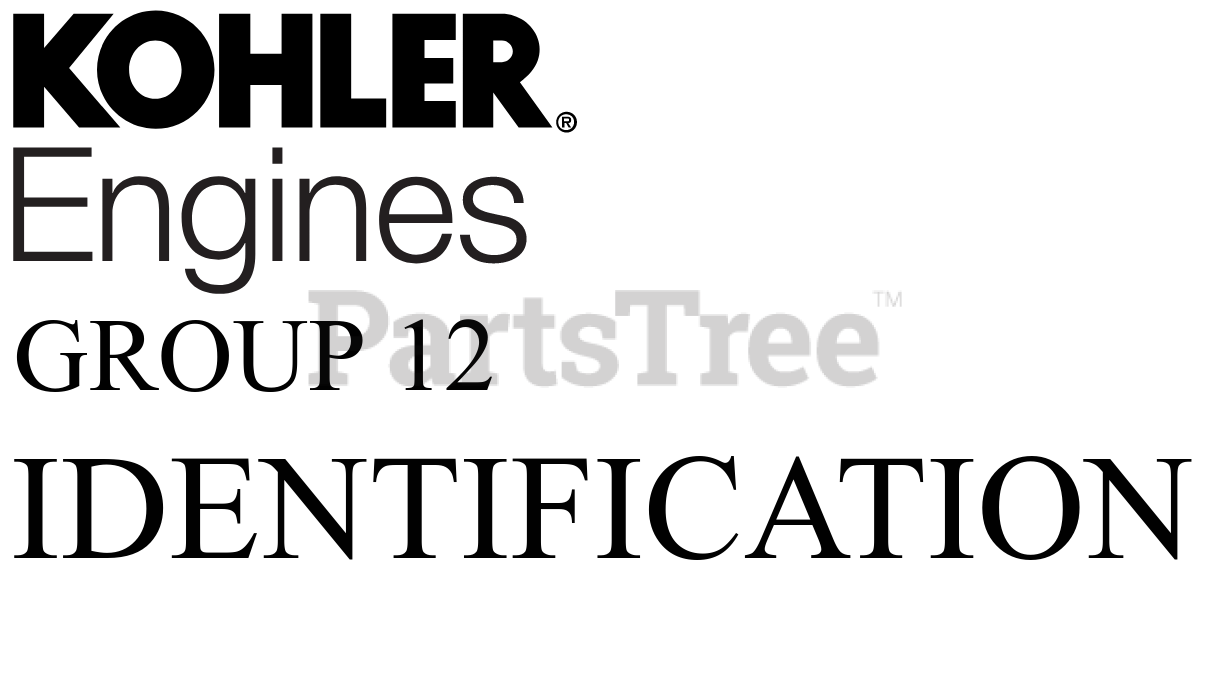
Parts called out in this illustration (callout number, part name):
NI	DECAL, SPEED
NI	DECAL, A/C
NI	DECAL, CAUTION
NI	LABEL, IGNITION-DISCONTINUED
NI	LABEL, CHOKE
NI	LABEL, RET. STARTER
